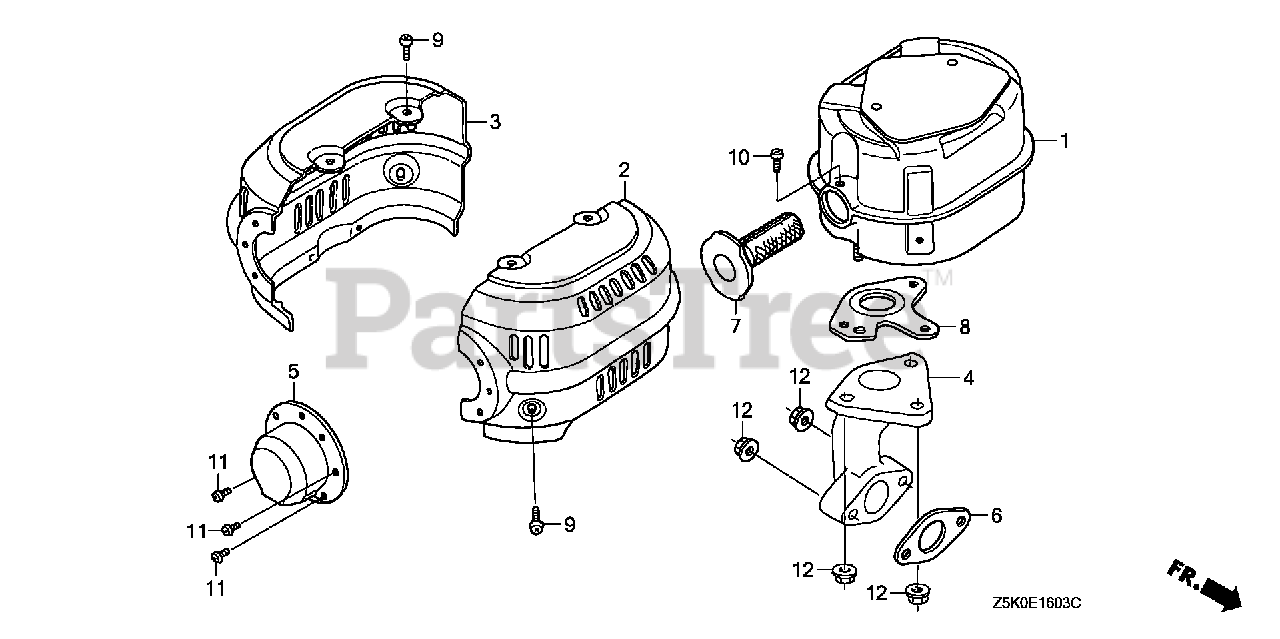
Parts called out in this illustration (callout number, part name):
1	MUFFLER
2	PROTECTOR, R. MUFFLER (STD)
3	PROTECTOR, L. MUFFLER (STD)
5	CAP, MUFFLER
6	GASKET, EX. PIPE
7	ARRESTER, SPARK
8	GASKET, MUFFLER (ARRESTER) (NIPPON LEAKLESS)
8	GASKET, MUFFLER (ARRESTER)(THAI LEAKLESS)
9	SCREW, TAPPING (5X8)
10	SCREW, TAPPING (5X8)
11	SCREW, TAPPING (4X6)
12	NUT, FLANGE (8MM)
